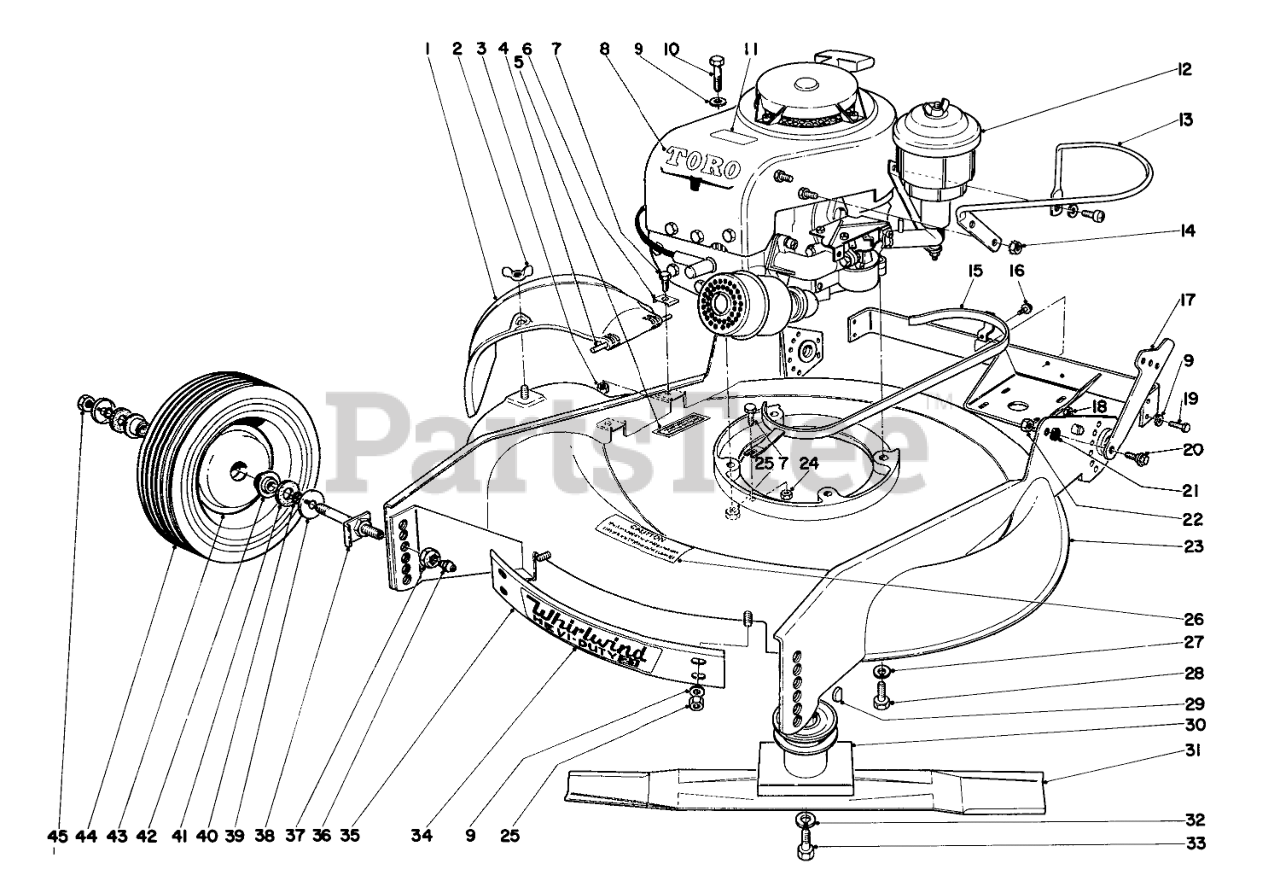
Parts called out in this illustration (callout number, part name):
1	Deflector
2	Wing Nut
3	Nut
4	HINGE PIN
5	Decal
6	Clamp
7	SCREW-HH
8	Decal
9	WASHER-PLAIN
10	SCREW-HH
11	Decal
12	Engine
14	NUT-KEPS
15	Belt Guide
16	Screw
17	Latch
18	NUT-LOCK NI
19	SCREW-HH
20	SCREW-SHOULDER
21	SPACER
22	Nut
23	Housing
24	Nut
25	Nut
26	Decal
27	WASHER-LOCK
28	SCREW-HH
29	KEY-WOODRUFF
30	Blade Retainer
31	Blade
32	WASHER-LOCK
33	SPECIAL SCREW
34	Decal
35	Guard
36	FITTING-GREASE
37	NUT-LOCK, NI
38	Spindle Ass-y. (Incl. Ref. #36)
39	SLINGER
40	O-RING
41	Washer
42	BEARING-BALL
43	Wheel Ass-y. w/Tire (Incl. Ref. #42 & 44)
44	1.75-8 SEMIPNEU TIRE
45	Nut
